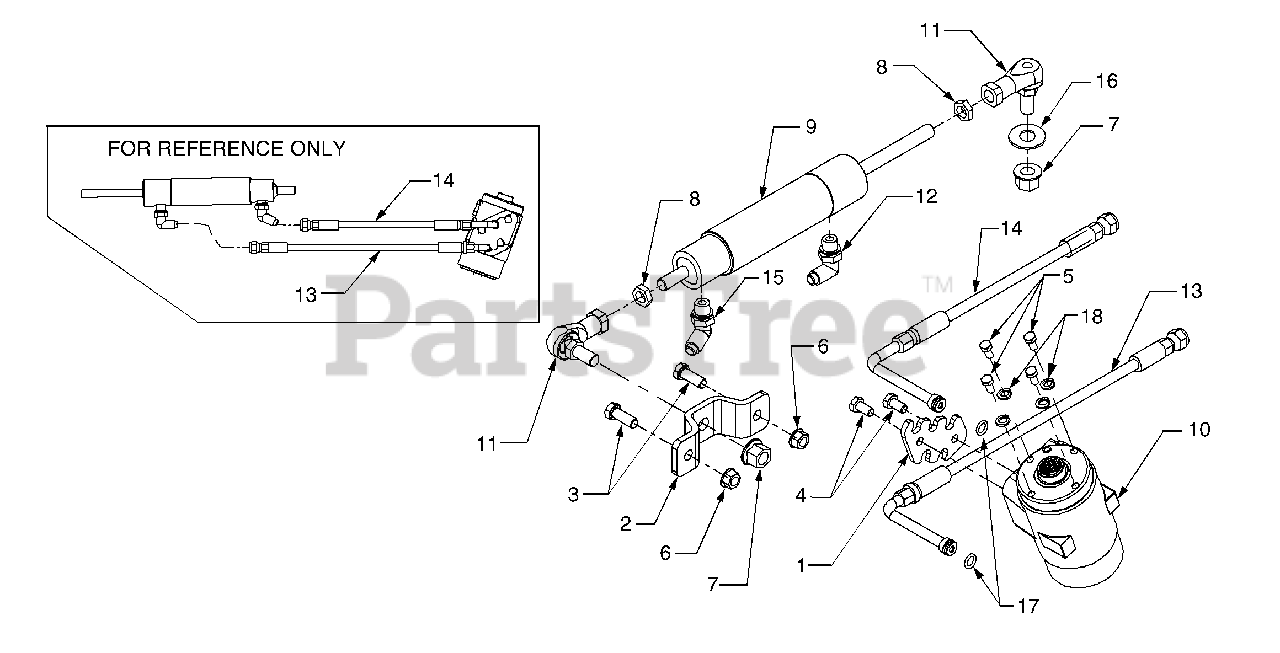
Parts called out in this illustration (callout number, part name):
1	Plate, Steering Pump Port
2	Bracket, Cylinder Mounting
3	Screw, Hex Cap 3/8-16 x 1.0 GR5
4	Screw, Hex Cap M8-1.25 x 16MM GR5
5	Screw, Hex Cap, M6 x 14MM
6	Nut, Hex Flange Lock, 3/8-16
7	Nut, Hex Flange Lock, M12 x 1.75
8	Nut, Hex, M12 x 1.75 RH
9	Cylinder, Steering
10	Pump, Hydraulic Steering
11	Ball Joint, 12MM x 1.75 RH
12	Fitting, 90 Degree Elbow
13	Hose, Front Steering
14	Hose, Rear Steering
15	Fitting, 45 Degree
16	Washer, Flat, .51 x 1.12 x .060
17	O-Ring, .426 x .566 x .070
18	Washer, Lock, 1/4"
